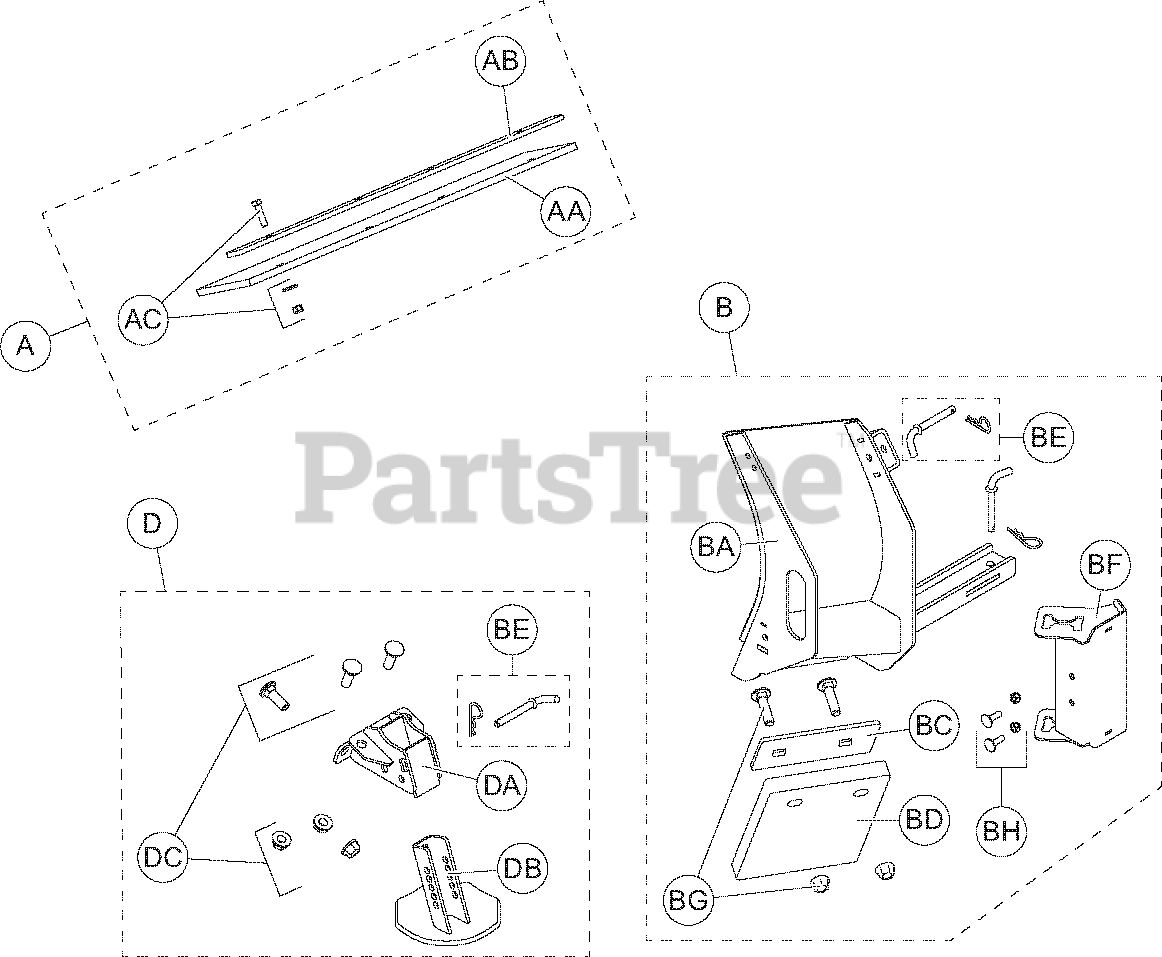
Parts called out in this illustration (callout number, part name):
A	KIT, RUBBER DEFLECTOR
AA	RUBBER DEFLECTOR
AB	DEFLECTOR, HOLD DOWN
AC	HARDWARE, DEFLECTOR
B	KIT, WINGS - VPLOW
BA	WING, REPLACEMENT LH
BC	BOLTING BAR
BD	CUTTING EDGE, WINGS
BE	PACKAGE, PIN
BF	WING HOLDER
BG	HARDWARE, CUTTING EDGE
BH	HARDWARE, WING HOLDER
D	KIT, SHOE V-PLOW
DA	BRACKET, SHOE
DB	SHOE STEM
DC	HARDWARE, SHOE
